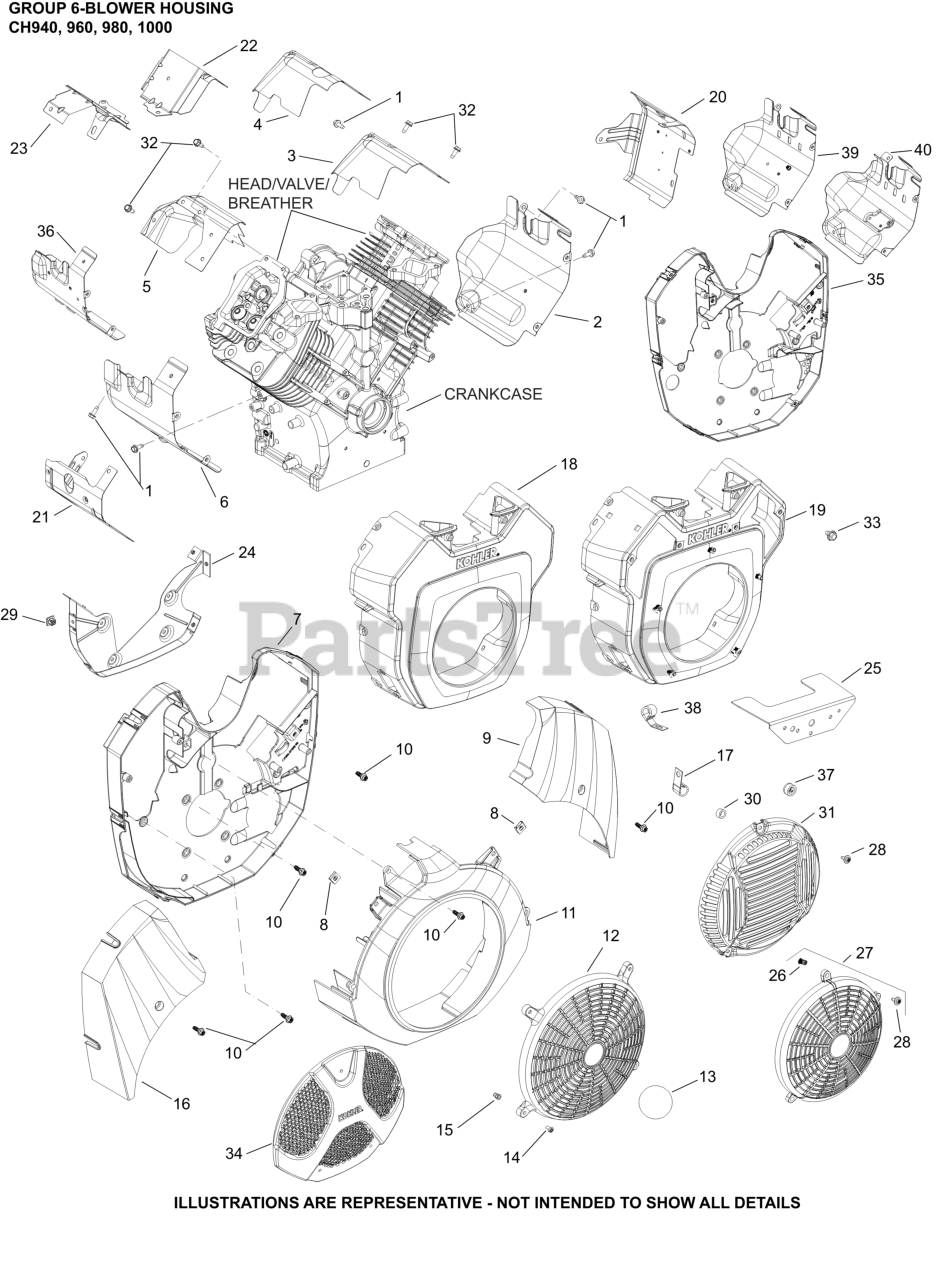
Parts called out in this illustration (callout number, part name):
1	SCREW, THREAD FORMING
4	BAFFLE, VALLEY #1 CYLINDER
5	BAFFLE, VALLEY #2 CYL-USE 62 063 40-S
6	BAFFLE, BARREL (#2 CYL)
7	SHROUD AND CLIP ASSEMBLY
8	CLIP, BAFFLE MOUNTING
9	SHROUD, #1 CYLINDER
10	SCREW, SHD THD FRM
11	KIT, BLOWER HOUSING
12	KIT, FIXED GUARD
14	SCREW, LBD SCKT PAN M5X0.8X10
16	SHROUD, #2 CYLINDER
26	INSERT, THREADED (M5)
40	BAFFLE, BARREL (#1 CYL)
NI	SCREW, FLG M6x1.0x20
